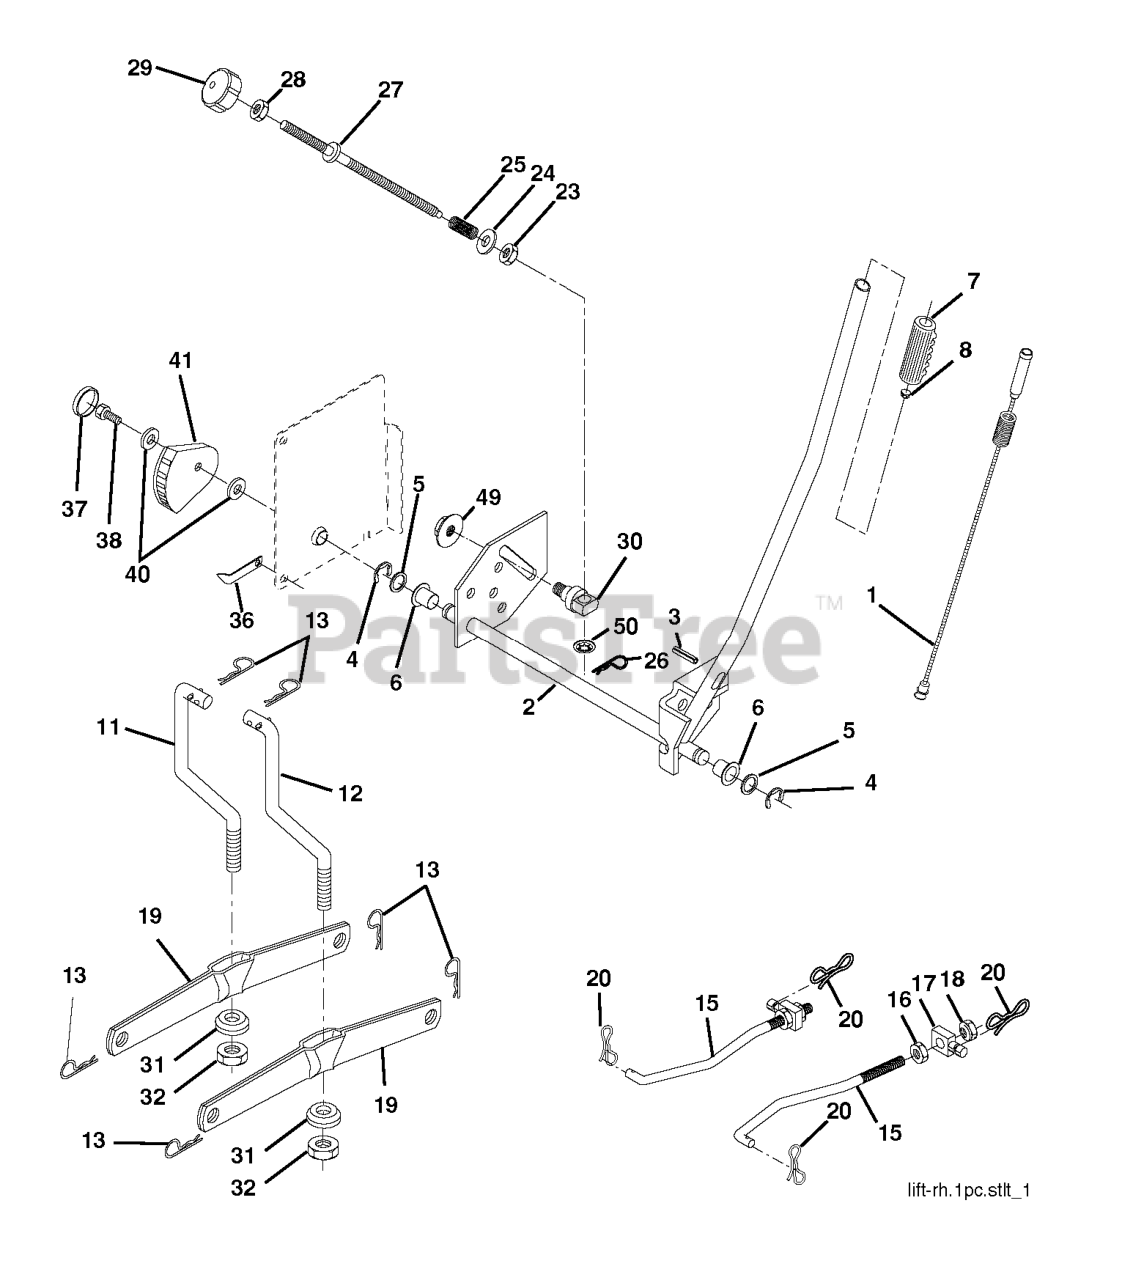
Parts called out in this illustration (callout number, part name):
1	PLUNGER.ASM.LIFT.LEVER.BLK.
2	SHAFT.ASM.LIFT.YT
3	PIN.GROOVE.5/16
4	RETAINING RING LT
6	BEARING.NYLON
7	GRIP HANDLE
8	REPL BY 532 12 59-25
11	LINK
12	LINK
13	RETAINER-SPRNG RB
15	LINK.SUSPENSION.FRONT
16	NUT.HEX.JAM.1/2-13
18	NUT.LK.W/WSH.1/2.
19	ARM.REAR.SUSPENSION
20	PIN.COTTER.7/16.BOW TI.
26	RETAINER CLIP
27	ROD ADJ LIFT
28	NUT
29	KNOB INF 3/8-16
31	BEARING.PIVOT.LIFT
32	NUT CROWNLOCK 3/8-24
36	POINTER, HEIGHT INDICATOR(2 2)
38	SCREW 5/16-18X1
41	HEIGHT INDICATOR
49	NUT
50	NUT PUSH M
